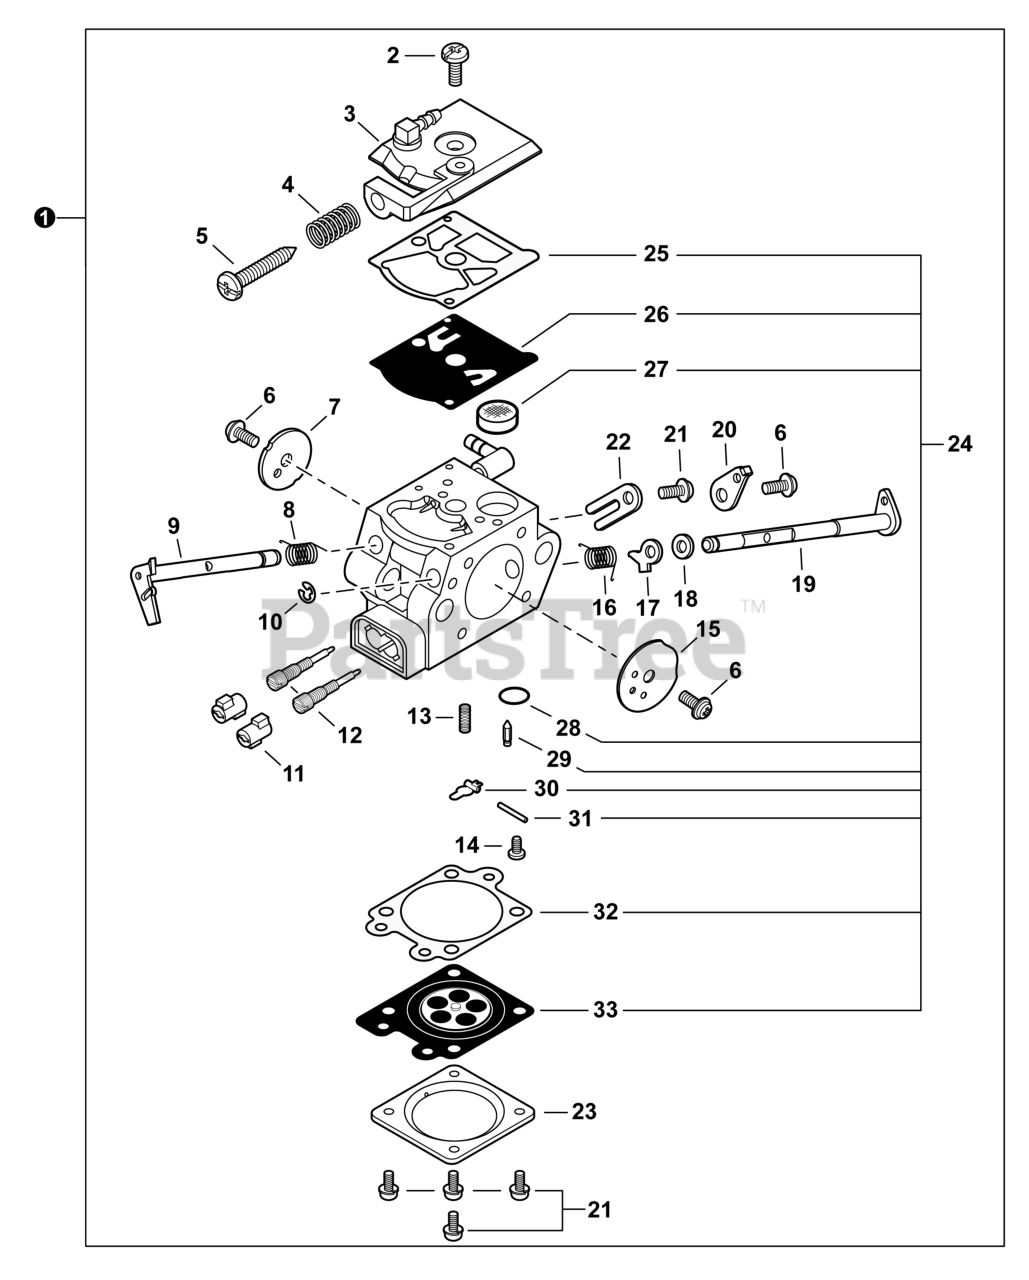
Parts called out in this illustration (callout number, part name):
1	CARBURETOR WT-985
3	COVER, FUEL PUMP
4	SPRING, IDLE ADJUST
5	SCREW, IDLE ADJUST
7	VALVE, THROTTLE
8	SPRING, THROTTLE RETURN
9	SHAFT, THROTTLE
11	CAP, LIMITER
12	NEEDLE, MIXTURE
13	SPRING, METERING LEVER
14	SCREW, METERING LEVER PIN
15	VALVE, CHOKE
16	SPRING, CHOKE RETURN
17	LEVER, FAST IDLE
19	SHAFT, CHOKE
20	LEVER, THROTTLE
22	CLIP, THROTTLE SHAFT
23	COVER, METERING DIAPHRAGM
24	REPAIR KIT, CARBURETOR
25	GASKET, FUEL PUMP
26	DIAPHRAGM, PUMP
27	SCREEN, FUEL INLET
28	PLUG, WELCH
29	VALVE, INLET NEEDLE
30	LEVER, METERING
31	PIN, METERING LEVER
32	GASKET, METERING DIAPHRAGM
33	DIAPHRAGM, METERING
